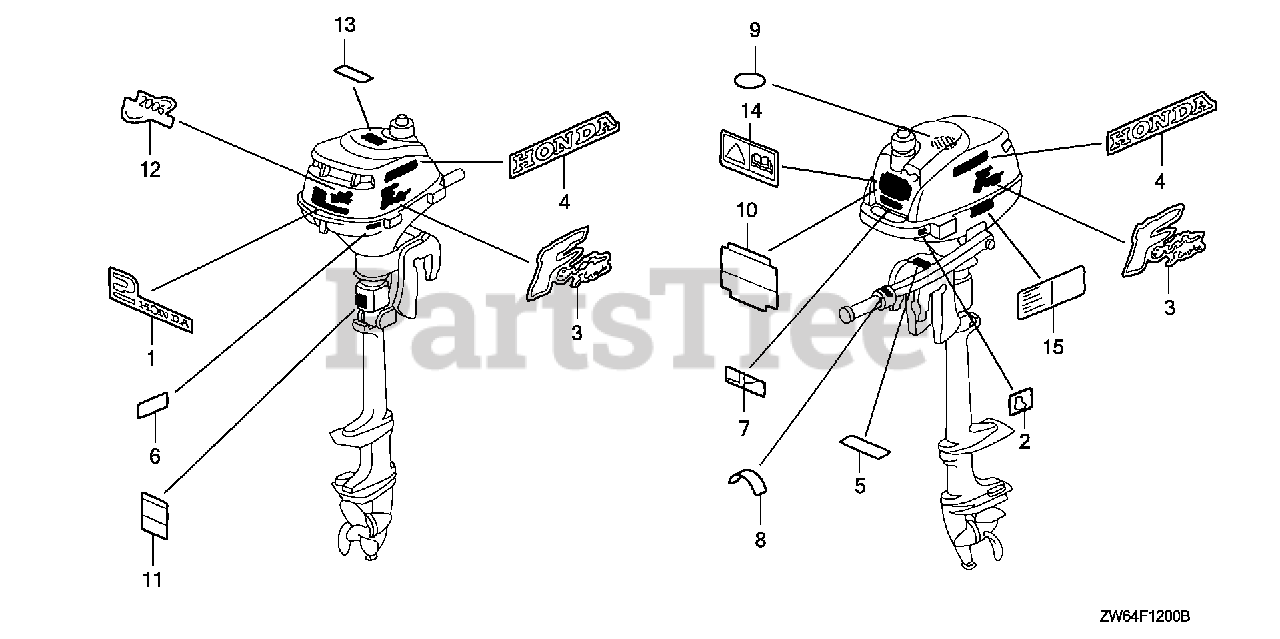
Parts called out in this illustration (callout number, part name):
2	MARK, EMERGENCY SWITCH INDICATION
3	MARK, SIDE
4	MARK, SIDE STRIPE (HONDA)
5	LABEL, SPECIFICATION
6	MARK, FUEL PETCOCK (E)
8	MARK, THROTTLE (GRIP TYPE)(E)
9	LABEL, RECOIL CAUTION
10	LABEL, OPERATOR CAUTION
11	MARK, EX. CAUTION (E)
